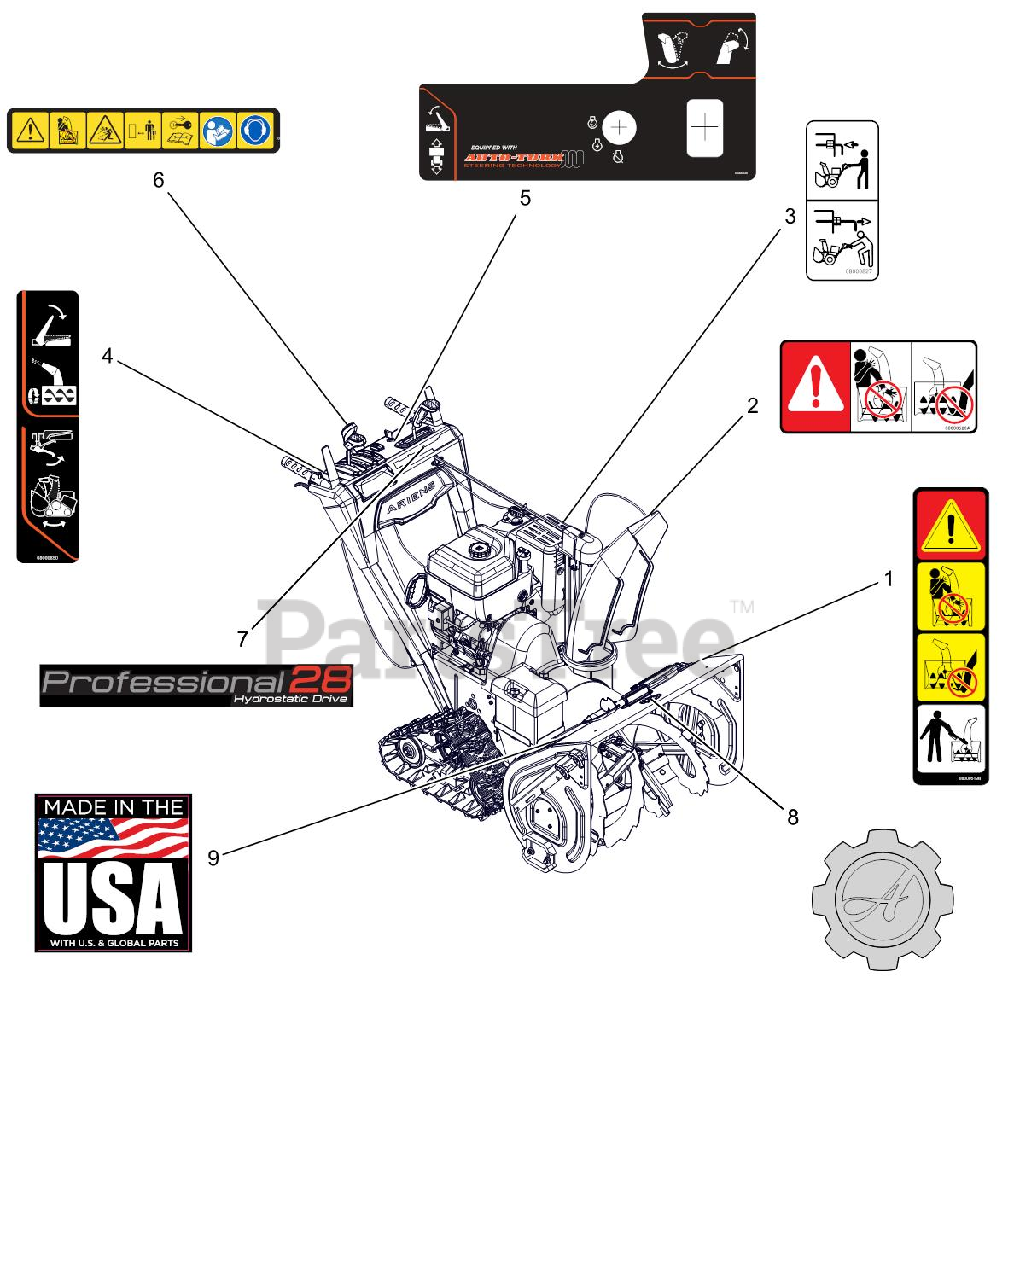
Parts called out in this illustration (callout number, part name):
1	DECAL, DANGER - ROTATING PARTS
2	DECAL, DANGER
3	DECAL, BYPASS
4	DECAL,CONTROL-RH TRACK
5	DECAL,CONTROL-LG QT2 12V
6	DECAL,DASH - SAFETY
7	DECAL, DASH - PRO HYDRO 28
8	DECAL, ARIENS-GEAR BADGE
9	DECAL, MADE IN USA
